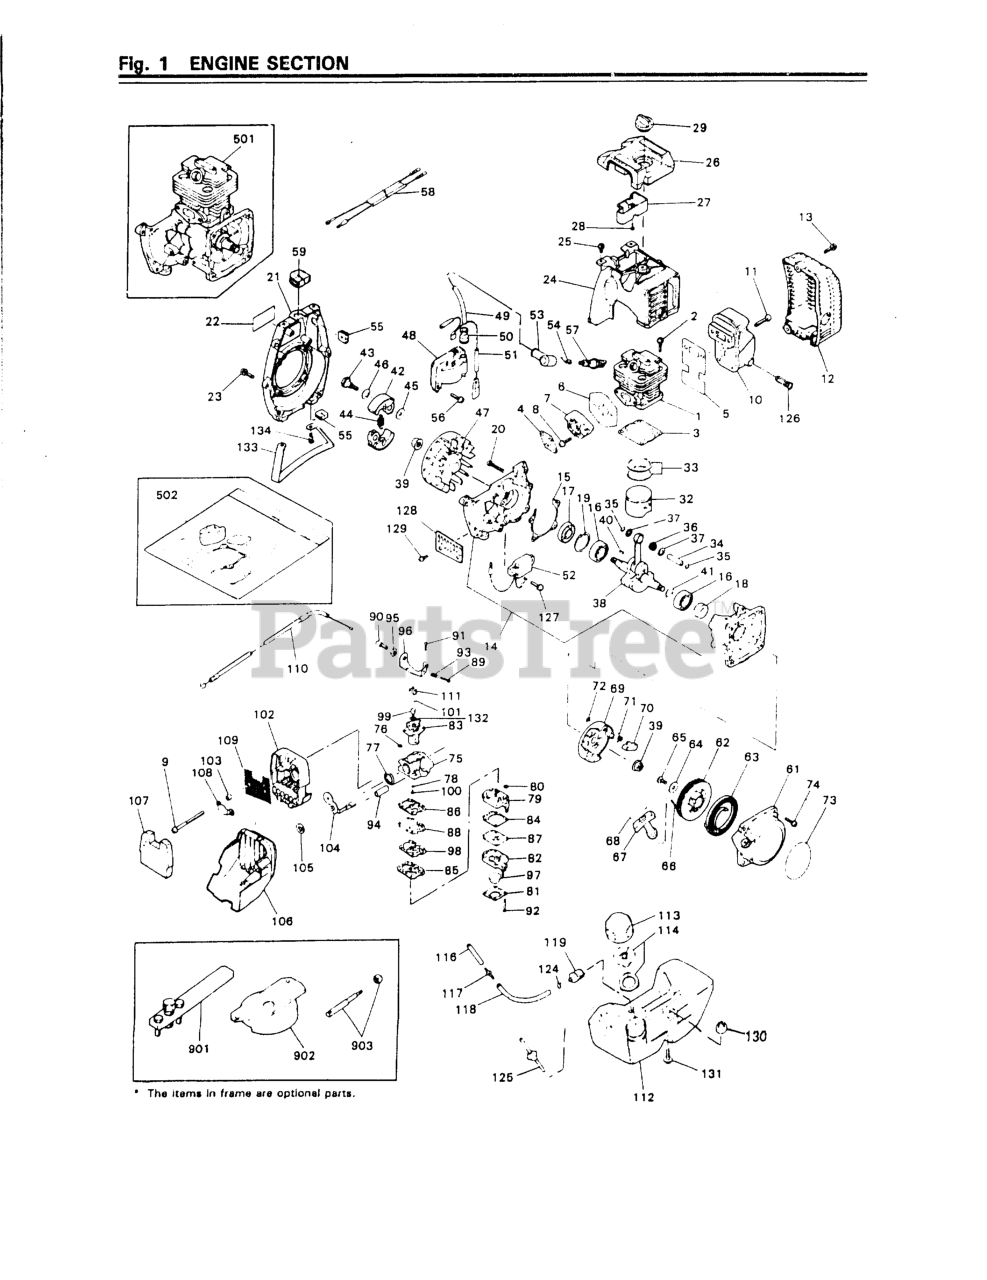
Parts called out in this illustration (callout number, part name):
1	CYLINDER (NLA)
2	SCREW (USE 0263-90520 )
8	SCREW (USE 0263-90520 )
11	SCREW
12	COVER, MUFFLER
13	SCREW (USE 0263-90520 )
14	CRANKCASE ASSEMBLY
17	SEAL, OIL (RPLS 1200-21220)
19	RING, SNAP, M32 x 1.2
20	SCREW, M5 x 30(RPLS 0263-00530
23	SCREW, M5 X 16
28	SCREW
32	PISTON
33	RING, PISTON
34	PIN, PISTON
35	RING, SNAP (RPLS 1101-41320)
36	BEARING
37	WASHER, THRUST (NLA)
38	CRANKSHAFT COMP
40	KEY
41	SHIM (NO LONGER AVAILABLE)
43	BOLT
45	WASHER, FLAT (USE 182303)
48	COIL ASSEMBLY
49	CORD HIGHTENS (NLA)
50	CAP
52	UNIT (RPLS -71310)
53	CAP, PLUG
54	SPRING PLUG (RPLS 3310-71320)
56	SCREW (USE 0263-90520 )
58	CORD
61	RECOIL ASSEMBLY
62	REEL
63	SPRING, SPIRAL
67	KNOB
70	RATCHET
71	SPRING, RETURN
72	E-RING
73	LABEL (NLA)
74	SCREW (USE 0263-90520 )
75	CARBURETOR
76	RING
77	RING, PACKING (NLA)
78	RING, O
79	KIT ONLY
80	SCREEN
81	COVER
82	BODY
83	VALVE ASSY (NO LONGER AVAIL)
84	KIT ONLY
85	GASKET, PLATE
86	GASKET, PUMP
87	DIAPHRAGM (USE 4810-81260)
88	DIAPHRAGM
89	SCREW, IDLE AD
90	SCREW, CABLE
91	SCREW
92	SCREW
93	SPRING, IDLE A
94	SLEEVE, MOUNT
95	NUT, CABLE ADJUSTER
96	BRACKET, IDLE
97	PUMP, PRIMING
98	PLATE, PUMP (NLA)
99	SWIVEL (USE -06040)
101	PLUG NEEDLE
103	SLEEVE
106	COVER, AIR FILTER (RPLS -82201
108	PLATE
110	CABLE COMP (RPLS 1633-83100)
111	CAP, CABLE END
114	VALVE COMPLETE
117	JOINT (NLA)
118	PIPE, SUCTION
119	5500-85400 (RRLS. 1750-85300)
124	CLIP (REPLACES 2841-31280)
126	ARRESTER (RPLS 5850-15140)
130	WASHER
131	SCREW, M5 X 22
132	WASHER
501	BLOCK, SHORT
502	KIT, GASKET
902	SET BLOCK (TOOL)
903	ROD ASSY
NI	CARB. REPAIR KIT
